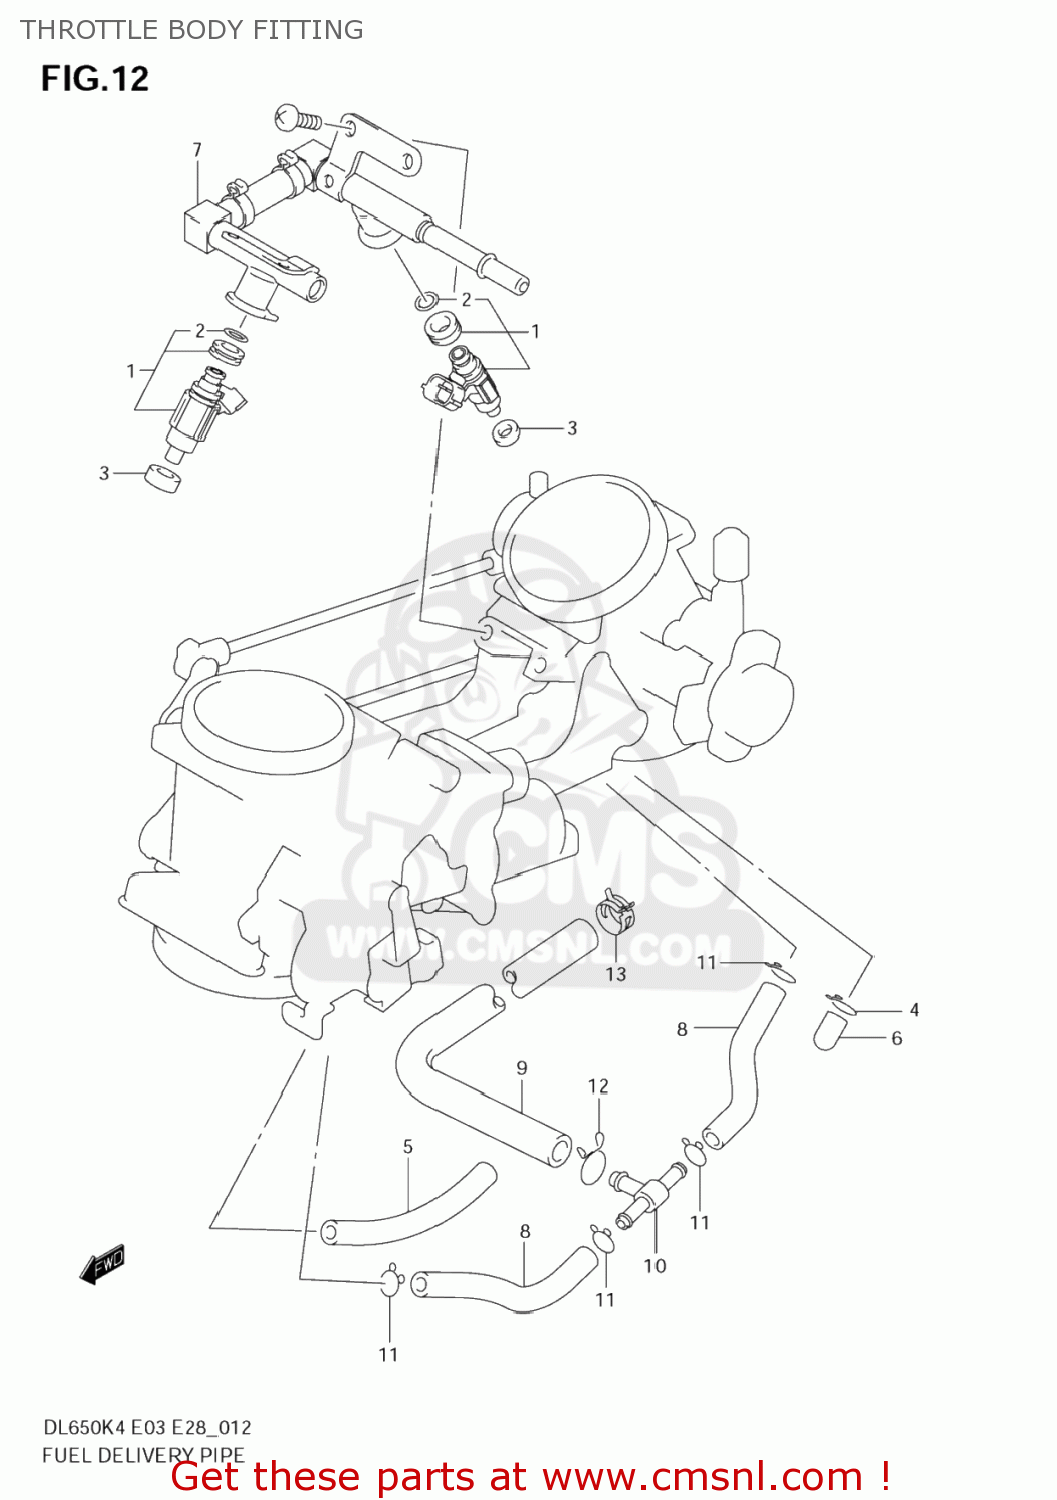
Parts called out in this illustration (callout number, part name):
1	INJECTOR ASSY
2	O RING
3	CUSHION,FUEL INJECTOR
4	CLIP
5	HOSE(L:425)
6	CAP
7	DELIVERRY PIPE
8	HOSE(3.2X7.4X225)
9	HOSE
10	NIPPLE
11	CLIP
12	CLIP
13	CLIP
